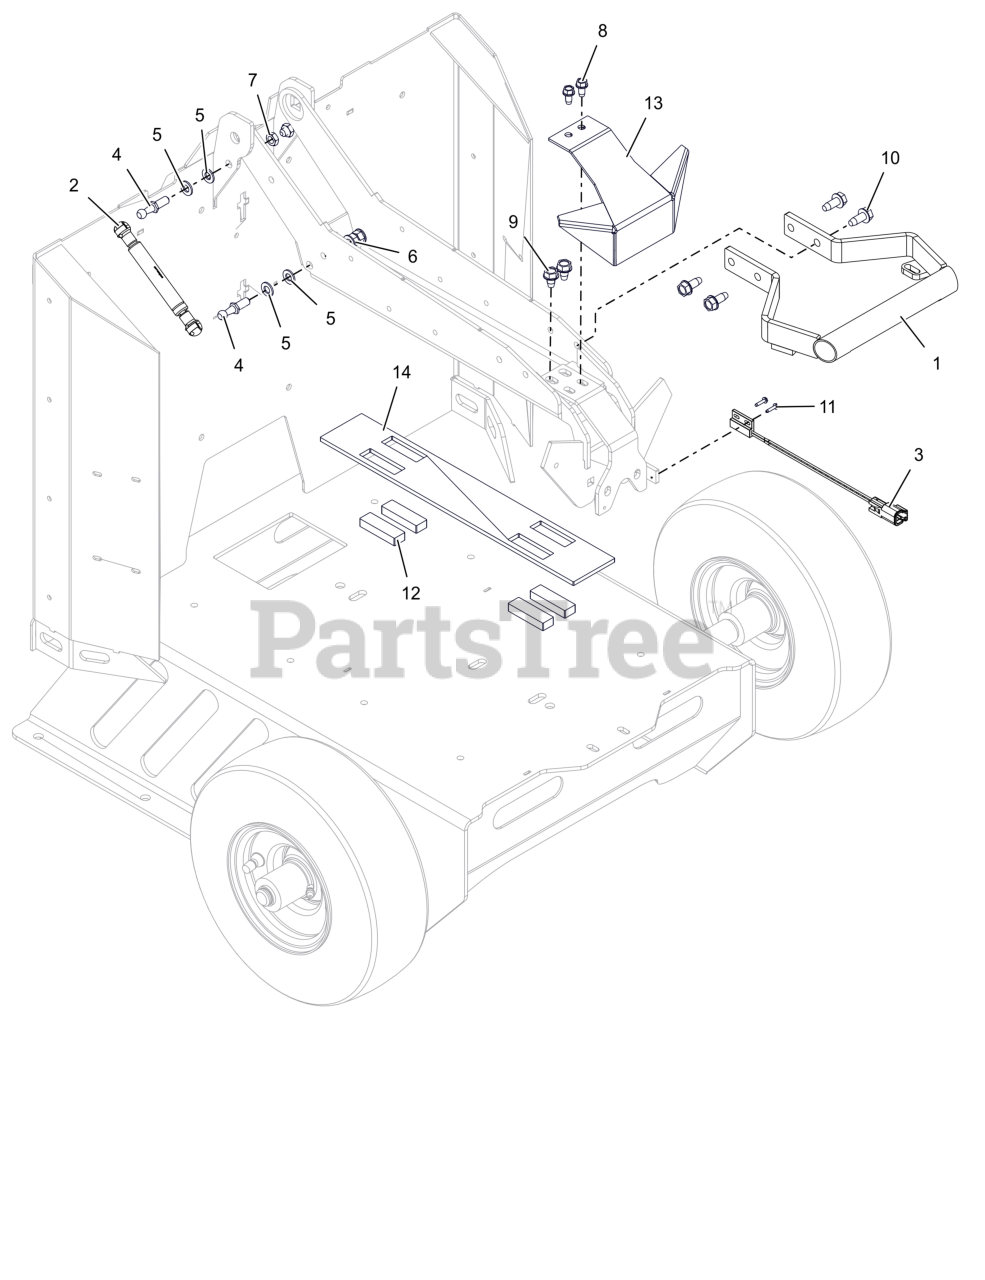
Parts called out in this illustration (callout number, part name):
1	WLDMT, HANDLE (BLUE)
2	DAMPER, GAS
3	SWITCH, MAGNETIC
4	STUD-BALL-THREADED
5	WSHR,FLT .323X.625X.062 ZCC
6	NUT,LK-CTR-FLG .31-18 GF ZCC
7	NUT-JAM .312-18 G2 ZCC
8	SCR-TAP .25-20X.50 HWH ZCC
9	SCR,TAP .312-18X.50 HWH TR ZCC
10	SCR,TAP .312-18X.75 HWH TR ZCC
11	SCR-TAP #4-40x.50 HWH ZCC
12	PAD, RUBBER
13	COVER, LATCH (BLUE)
14	PAD, RUBBER
